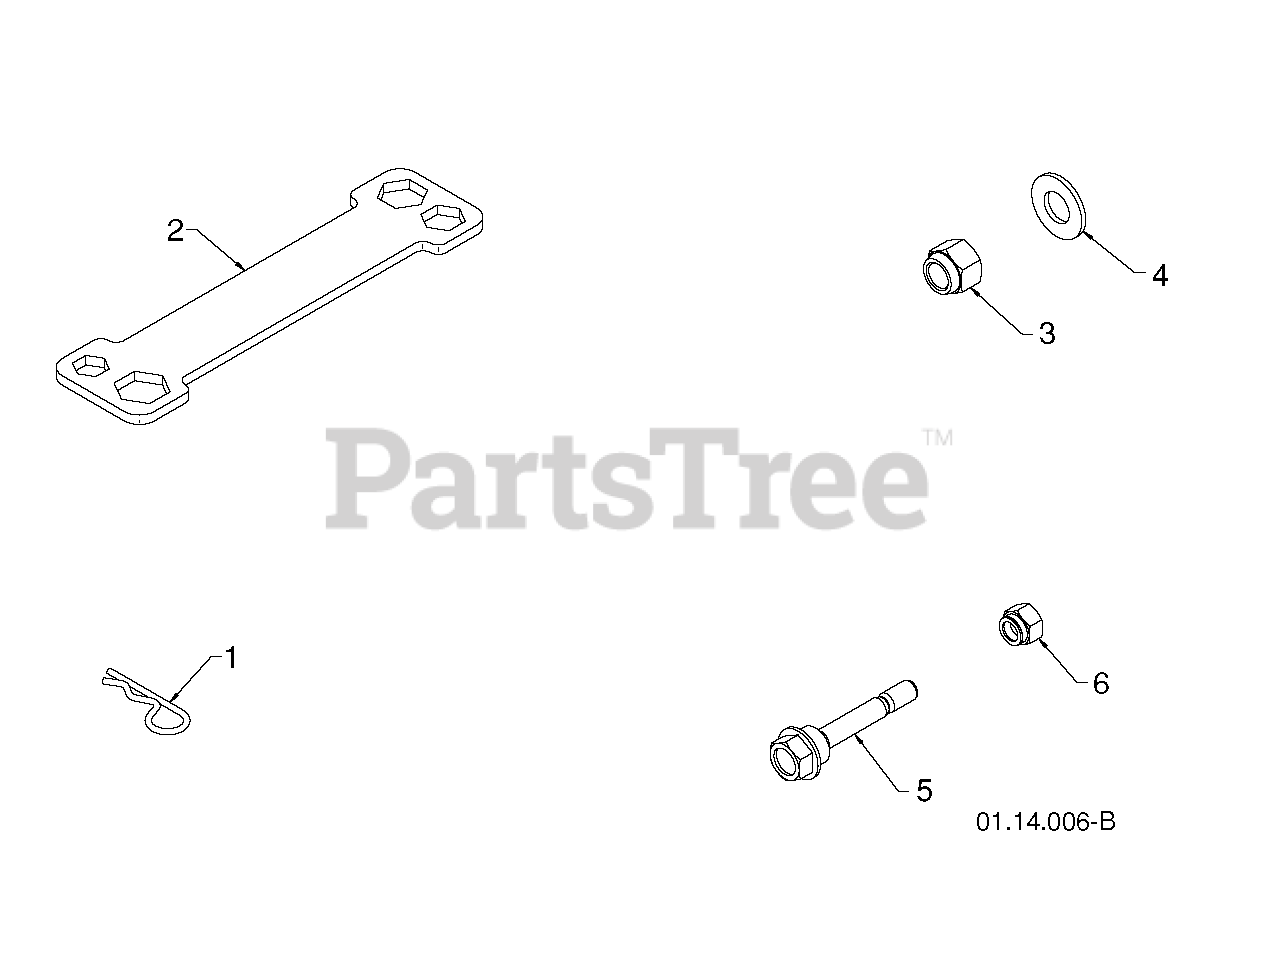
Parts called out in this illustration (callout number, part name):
1	SPRING RETAINER
2	WRENCH.SNOWTHROWER.ZINC.YZ
3	NUT
4	WASHER
5	BOLT.SHOULDER.SHEAR.1/4-20.
6	LOCKNUT.NYLOC.1/4-20
